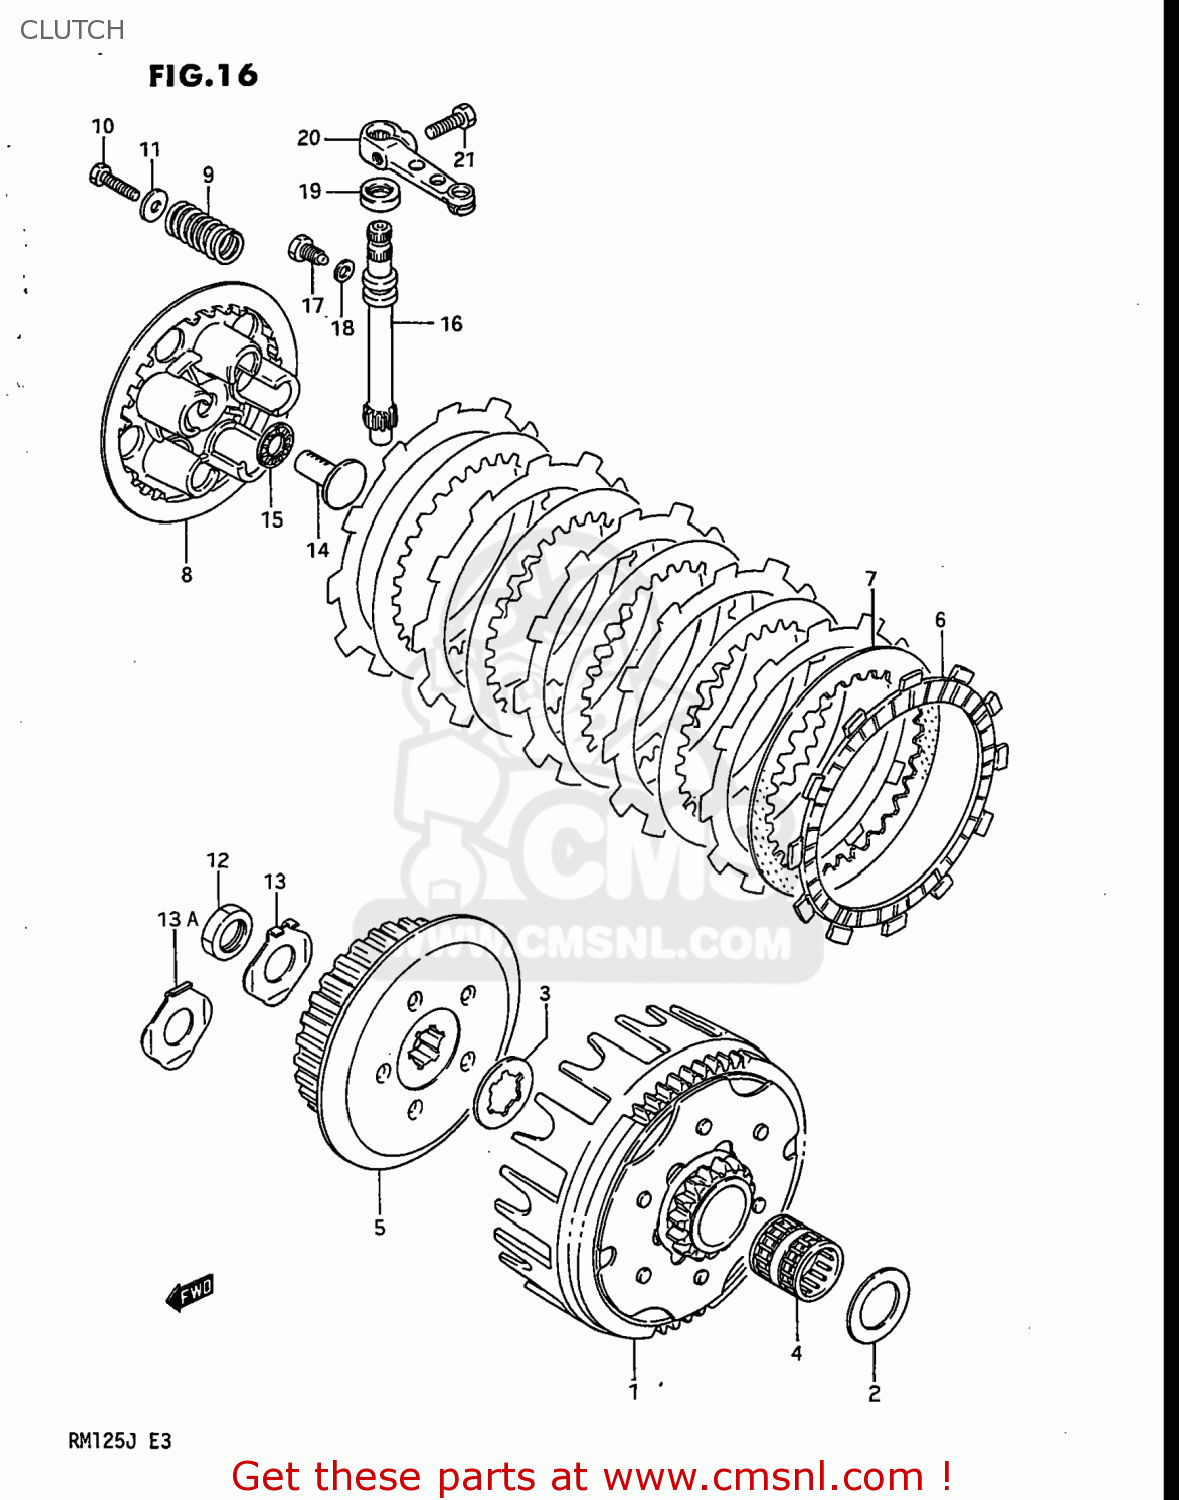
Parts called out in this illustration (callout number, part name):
1	GEAR ASSEMBLY,PRIMARY DRIVE
2	WASHER,THRUST
3	WASHER,LOCK
4	BEARING(20X25X26)
5	HUB,CLUTCH SLEEVE
6	PLATE,CLUTCH DRIVE (NAS)
7	PLATE,DRIVEN(T:1.4)
8	DISC,CLUTCH PRESSURE
9	SPRING
10	BOLT(5X16)
11	WASHER (5.5X16X1.2)
12	NUT
13	WASHER
13A	WASHER
14	RACK,CLUTCH RELEASE
15	BEARING(10X22X2.8)
16	PINION,CLUTCH RELEASE
17	BOLT
18	GASKET(6.2X11X1).2 (NAS)
19	SEAL,OIL(10X17X5)
20	ARM,CLUTCH RELEASE
21	BOLT
